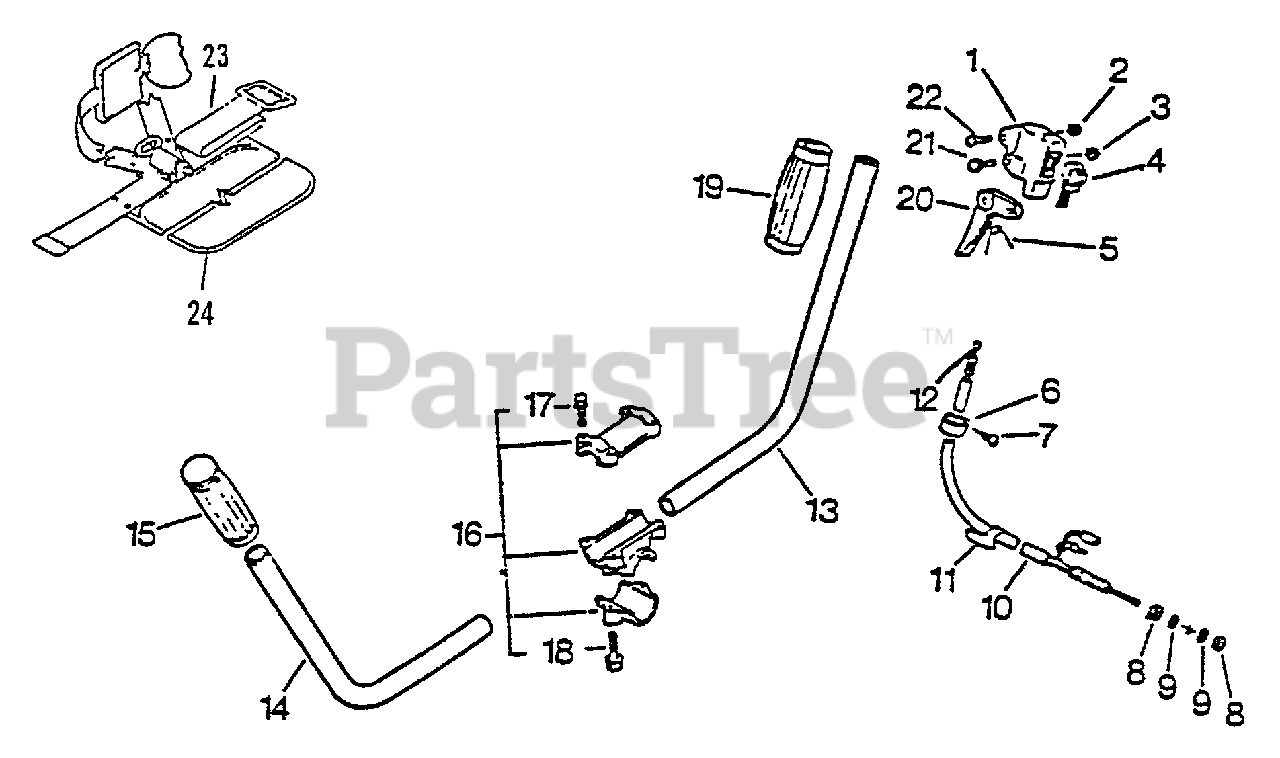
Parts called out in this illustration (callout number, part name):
1	BRACKET, THROTTLE
2	LOCKNUT - 5
4	IGNITION SWITCH ASSY
5	SPRING, TRIGGER
7	SCREW - 5X10
8	LOCKNUT - 6
9	WASHER - 6
10	TUBE - VINYL
12	CABLE, THROTTLE
14	HANDLE, FRONT - LEFT
15	GRIP, HANDLE - LEFT
16	HANDLE BRACKET KIT
17	BOLT - 5X25
18	BOLT - 6X30
19	GRIP, HANDLE
20	TRIGGER, THROTTLE
21	SCREW - 5X25
22	SCREW - 5X30
23	CUSHION
24	SHOULDER STRAP ASSY
